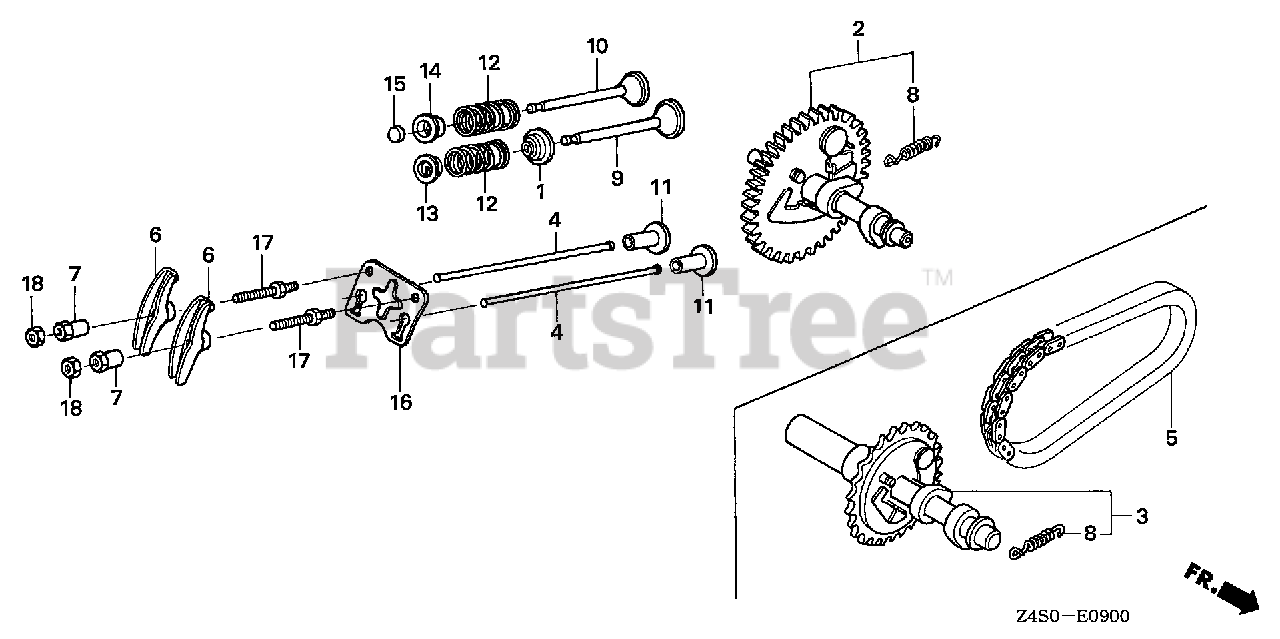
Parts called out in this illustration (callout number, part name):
1	SEAL, VALVE STEM
2	CAMSHAFT ASSY.
4	ROD, PUSH
6	ARM, VALVE ROCKER
7	PIVOT, ROCKER ARM
8	SPRING, WEIGHT RETURN
9	VALVE, IN.
10	VALVE, EX.
11	LIFTER, VALVE
12	SPRING, VALVE
13	RETAINER, IN. VALVE SPRING
13	RETAINER, VALVE SPRING (EXHAUST SIDE)
14	RETAINER, EX. VALVE SPRING
15	ROTATOR, VALVE
16	PLATE, PUSH ROD GUIDE
17	BOLT, PIVOT (8MM)
18	NUT, PIVOT ADJ.
